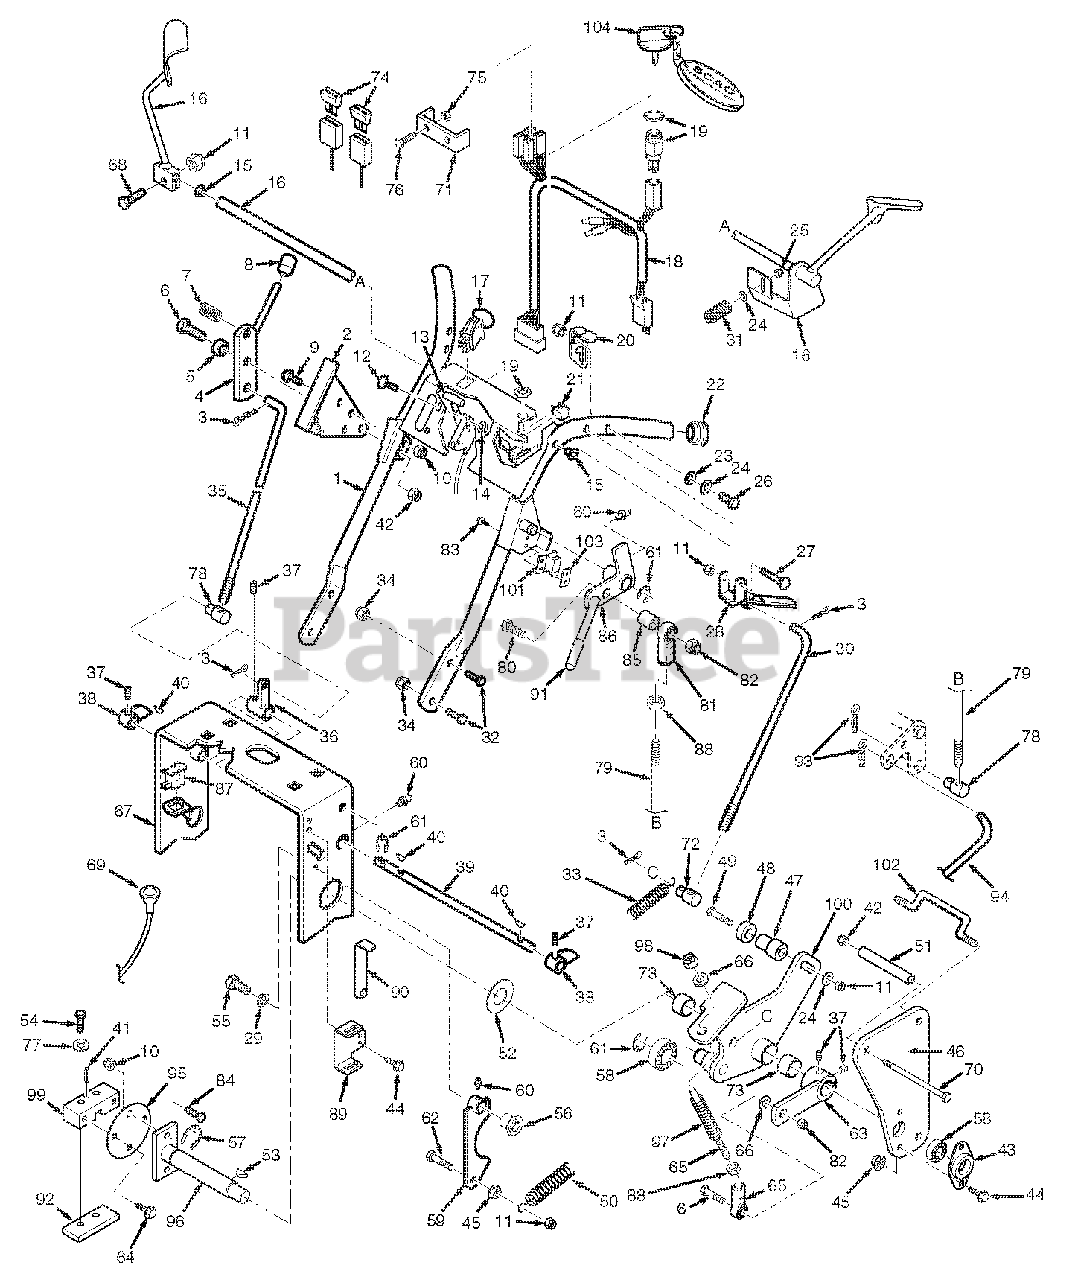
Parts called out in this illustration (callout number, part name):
1	Upper Handle Wlmt. W/Decals
2	Quadrant, Speed Control
3	Hairpin, .094 x 1.19
4	Lever, Speed Adjustment
5	Bushing, Speed Adjustment Lever
6	Hex Head Bolt, 3/8-16 x 1.5"
7	Ball Plunger
8	Knob, Speed Adjustment
9	Capscrew, 1/4-20 x 3/4" FHHS
10	Nut, 1/4-20 Elastic Stop
11	Nut, 5/16-18 Elastic Stop
12	Screw, #10-32 x 1/2" PW HD
13	Throttle Control
14	Nut, #10-32 Serr. Flange
15	Bushing
16	Handle, Oper. Presence-RH
16	Handle, Oper. Presence-LH
17	Switch, Electric Clutch Engage
18	Wire Harness, Manual Start
18	Wire Harness, Electric Start
19	Key Switch, Manual Srt. (inc. Hdw)
19	Key Switch, Electric Srt. (inc. Hdw)
20	Neutral Latch-RH
20	Neutral Latch-LH
21	Switch, Neutral Interlock
22	Plug, Handlebar
23	Washer, Curved Spring
24	Flat Washer
25	Nut, 5/16-18 Elastic Stop
26	Hex Head Bolt, 5/16-18 x 2"
27	Hex Hd. Bolt, 5/16-18 x 2.5"
28	Lever, Steering Control
29	Lockwasher, 3/8 Spring
30	Rod, Steering Control
31	Spring, Operator Presence
32	Capscr., 3/8-16 x 1" Ser. Flange
33	Spring
34	Nut, 3/8-16 Serr. Flange
35	Rod Speed Control
36	Bellcrank, Speed Control
37	Setscrew, 1/4-28 x .25"
38	Cam, Speed Control
39	Jackshaft, Speed Control
40	Key, 1/8 x 1/2" Woodruff
41	Roll Pin, 3/16-.75
42	Nut, Elastic Stop 3/8-16
43	Flange, Bearing
44	Capscrew, 5/16-18 x 1" Serr. Flg.
45	Nut, 5/16-18 Serrated Flange
46	Plate, Side
47	Spacer, Neutral Bearing
48	Bearing, Speed Ctrl. Bellcrank
49	Hex Head Bolt, 5/16-18 x 1-3/4"
50	Spring, Return
51	Spacer, Side Plate
52	Flatwasher, .766 x 1.25 x .035
53	Key, Woodruff, 3/16 x .75
54	Bolt, Hex Head, 1/4-20 x 1.25"
55	Bolt, Hex Head, 3/8-16 x 1"
56	Bushing, Brake
57	Clip, Retaining .750 diameter
58	Bearing, Ball Neutral Return
59	Cam, Neutral (incl. grease ftng.)
60	Grease Fitting, 1/4-28 UNF
61	Retaining Ring, 5/8"
62	Hex Head Bolt, 5/16-18 x 1"
63	Lever, Speed Control
64	Bolt, Hex Head 1/4-20 x.75"
65	Linkage Assembly
66	Flat Wshr., 15/16 x .3906 x 12 ga
67	Deck, Engine 20" Wide
68	Hex Head Bolt, 5/16-18 x 1.25"
69	Choke Control
70	Bolt, Hex Head 3/8-16 x 4.25"
71	Fuse Holder - 21KAE
72	Swivel Joint, Steering Rod
73	Bushing
74	Blade Fuse, 20A - 22FSE
75	Nut, #10-32 Elastic Stop - 2FSE
76	Screw, #10-32 x 1.5" Phillips - 22FSE
77	Lockwasher, 1/4"
78	Swivel Joint
79	Rod, Brake Lever
80	Hex Hd. Bolt, 3/8-16 x 2"
81	Ball Joint, RH Thread
82	Nut, 3/8-16 Elastic Stop
83	Screw #10-32 Sltd Hex Wshr Hd
84	Bolt, 1/4-20 x .75"
85	Spacer
86	Parking Brake Lever w/Grip & Grease Fitting
87	Switch, Safety
88	Nut, 3/8-24
89	Mounting Bracket, Wrench
90	Wrench
91	Grip, Parking Brake
92	Plate, Threaded
93	Hairpin, .094 x 1.62"
94	Rod, Lower Brake
95	Plate, Coupler
96	Shaft, Pump Control
97	Spring
98	Nut, 3/8-16 Elastic Stop
99	Block, Pump Control
100	Control, LH (inc. bush. & decal)
100	Control, RH (inc. bush. & decal)
101	Switch, Parking Brake
102	Rod, Offset
103	Plate, Threaded
104	Key Chain with Keys
104	Key with Shroud
